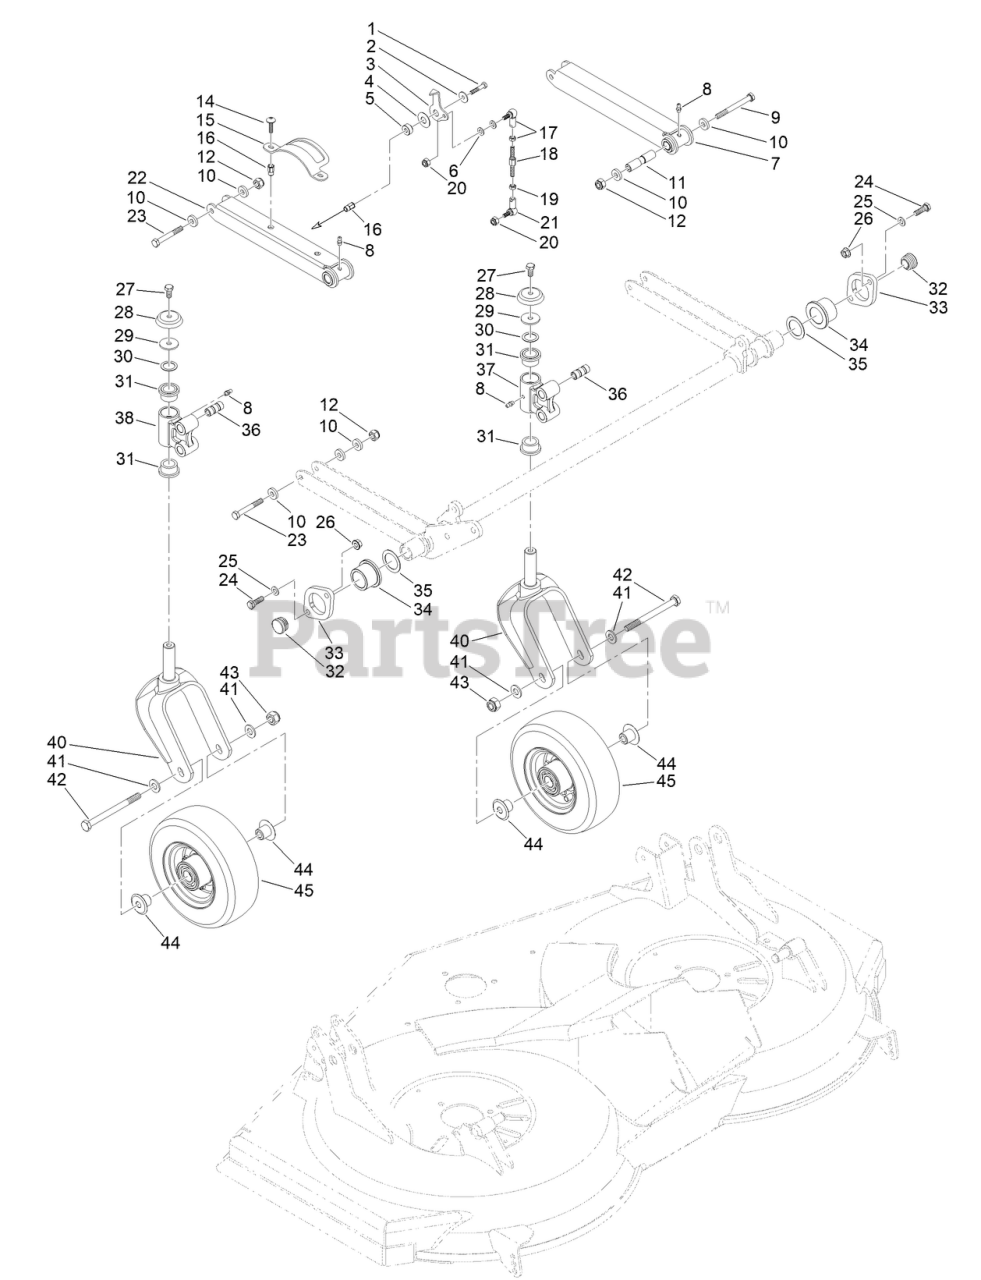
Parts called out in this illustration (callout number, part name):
2	WASHER
3	INDICATOR, HOC
4	WASHER, BELLEVILLE
5	BUSHING
6	WASHER
7	ARM ASSY, RH CASTOR WHEEL
8	FITTING-GREASE
10	WASHER
11	PIVOT, ARMS
15	BRACKET, HOC DECAL
16	INSERT-THREADED
17	TIE, ROD-END
21	ARTICULATION
22	ARM ASSY, LH CASTOR WHEEL
25	WASHER
28	GUARD, CASTOR WHEEL
29	WASHER
30	SPACER
31	BUSHING
33	FLANGE, BAR
34	BUSHING
36	PIVOT, JOINT
37	JOINT, RH CASTOR WHEEL
38	JOINT, LH CASTOR WHEEL
40	YOKE, CASTOR WHEEL
41	WASHER
44	BUSHING
45	CASTOR WHEEL ASSY
